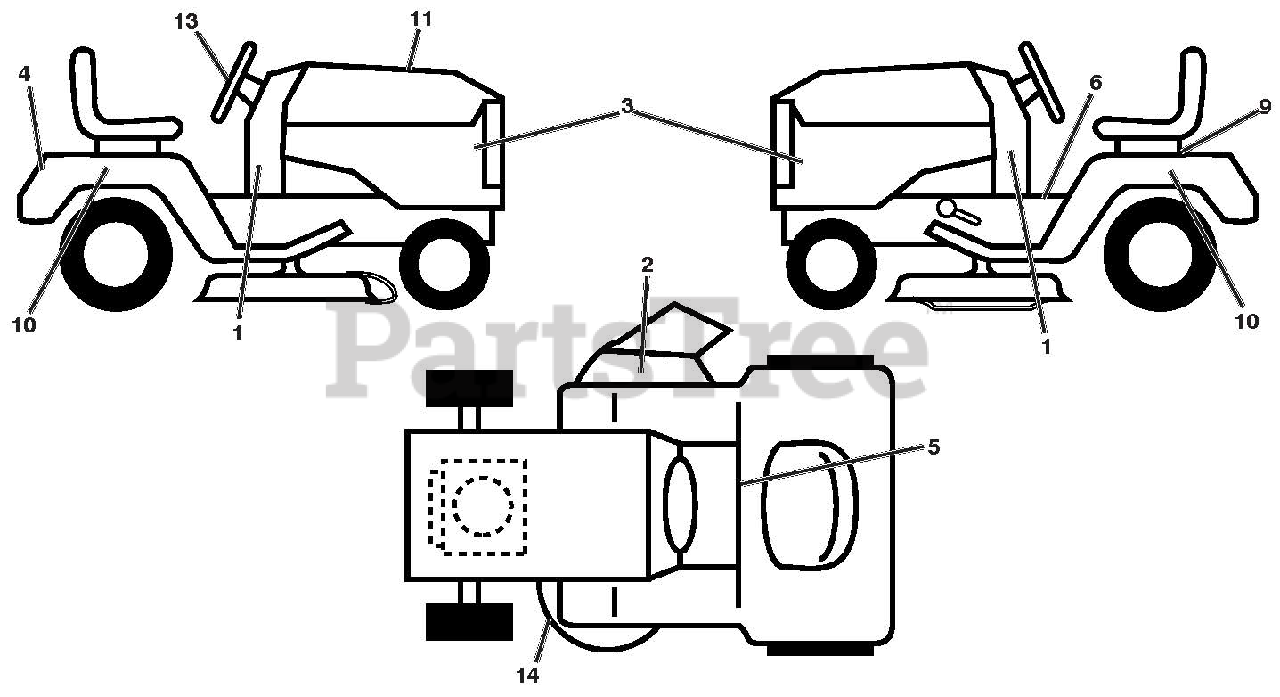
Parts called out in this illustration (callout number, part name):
2	DECAL DECK/DEFLECT. WARNING
3	DECAL.SDPNL.PWRDBY KOHL.ARIENS
4	DECAL.FENDER.REAR.ARIENS
5	DECAL.FENDER
6	DECAL, FENDER WARNING
9	DECAL.BAT.DAN/POI P/L SYM.WPN
10	DECAL FENDER SIDE
13	DECAL.WHEEL.STEER.ARIENS
14	DECAL.V-BELT.SCH.
